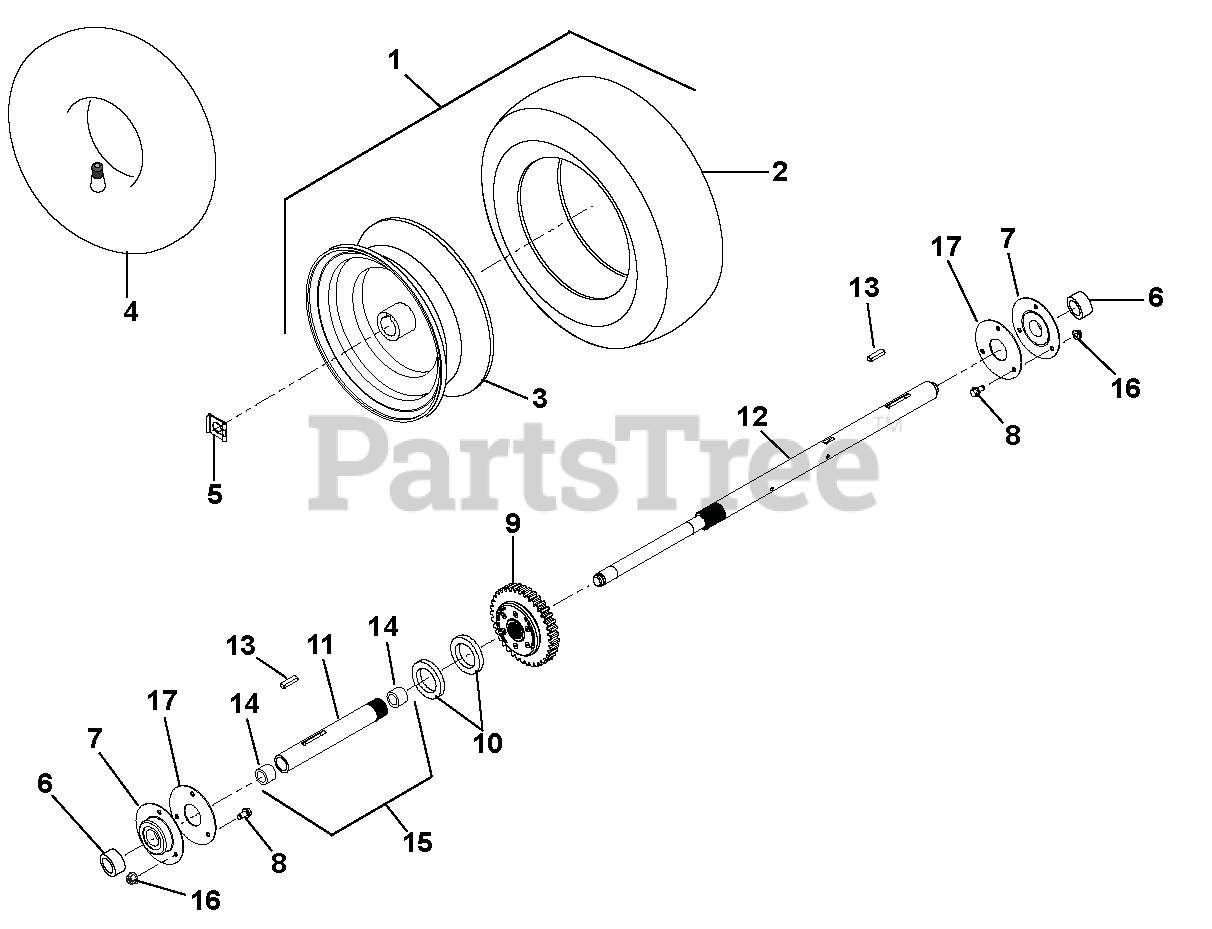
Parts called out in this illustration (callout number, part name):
1	TIRE/WHEEL,RH 16X4.8-8 DIFF T2
2	TIRE, 4.80-8 K478
3	HUB, WHEEL - 16X4.8-8 DIFF
4	TUBE
5	CLIP, SNAP .625 DIA
6	SPACER, PRO AXLE BEARING
7	BRG-FLG 1.003/1.000 3 BOLT
8	@BLT-HEX .25-20X.75 GR5 YWZC
9	DIFFERENTIAL, AUTOMATIC
10	WSHR-FL-STL- 1.062X2.0X.134 YZ
11	AXLE, SHORT-PRO AUTO DIFF
12	AXLE, LONG-PRO AUTO DIFF
13	KEY-RECT .25X.188X1.00
14	BSHG-SLV .706X.764X.75 BRZ
15	AXLE, SHORT-AUTO W/BUSHINGS
16	@NUT-LK-TOP-FLG .25-20 YWZC
17	PLATE, BEARING SPACER
